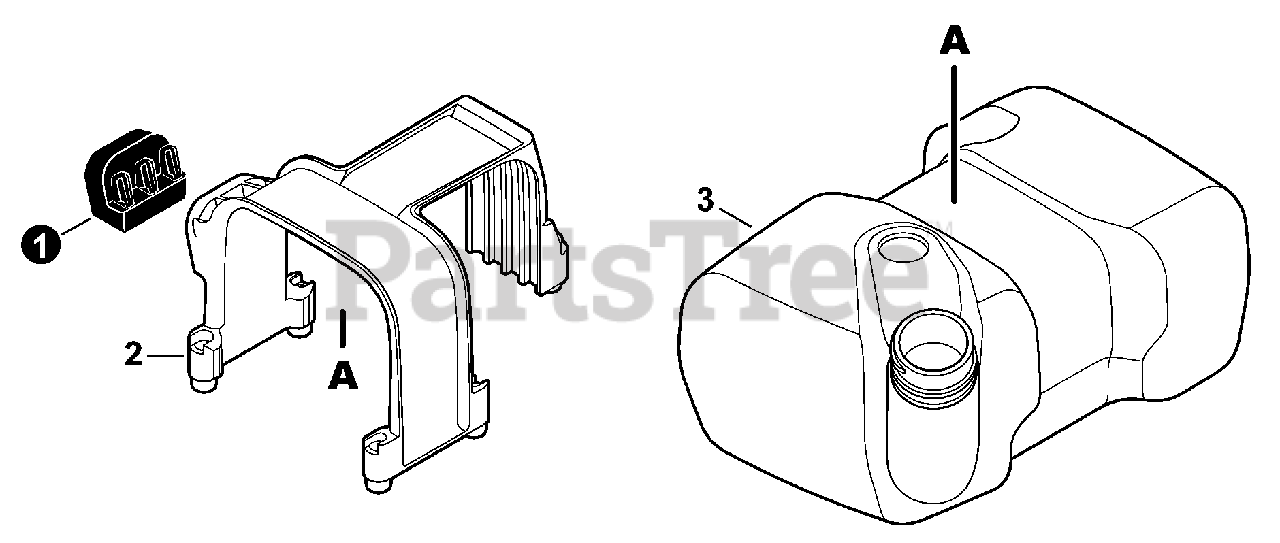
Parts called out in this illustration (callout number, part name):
1	CUSHION
2	RETAINER, FUEL TANK
3	TANK, FUEL
